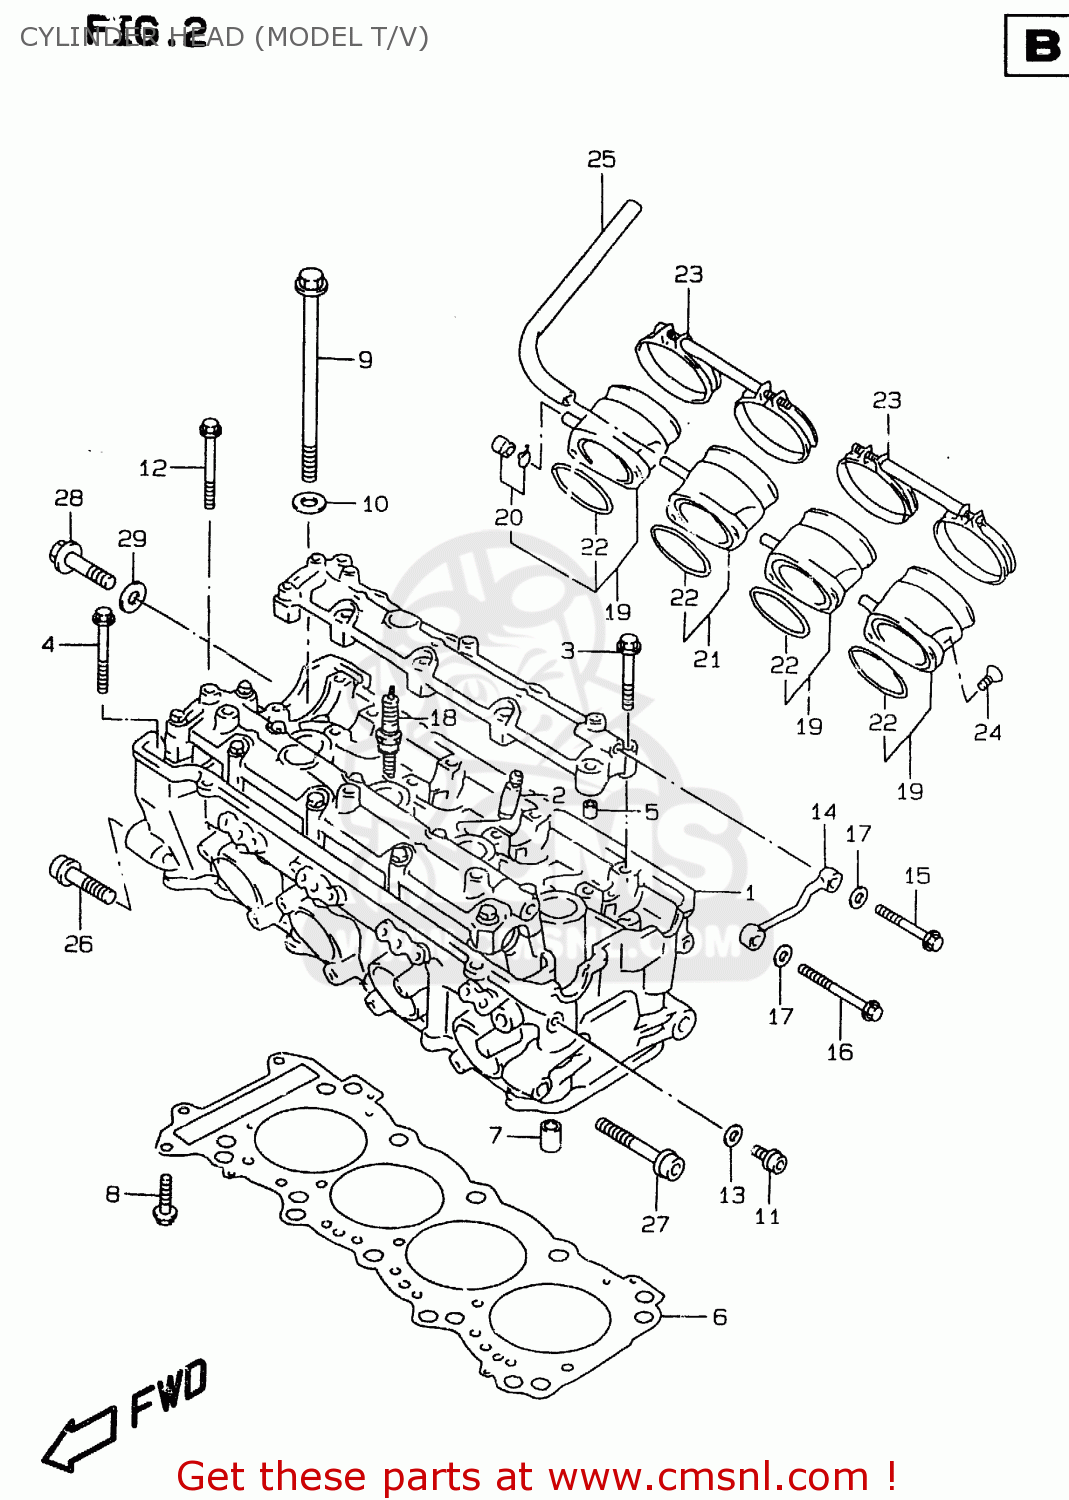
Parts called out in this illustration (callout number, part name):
1	HEAD ASSEMBLY,CYLINDER
2	GUIDE,VALVE
3	BOLT(6X39)
4	BOLT(6X45)
5	PIN(6.2X8X16)
6	GASKET,CYLINDER HEAD (T
7	PIN
8	BOLT
9	BOLT(10X160)
10	WASHER(10.5X19X2)
11	BOLT
12	BOLT,CYL.OIL P
13	GASKET(5.8X13X1.2) (NAS)
14	PIPE,CYLINDER HEAD OIL
15	BOLT
16	BOLT (6X45)
17	WASHER
18	PLUG,SPARK(CR8E)
19	PIPE ASSY,INTAKE
20	CAP
21	PIPE ASSY,INTAKE NO.3
22	O RING(D:2.4,ID:44)
23	CLAMP,INTAKE PIPE
24	SCREW
25	HOSE,VACUUM
26	BOLT
27	BOLT
28	BOLT,CYL HEAD SIDE FACE
29	WASHER,HEAD COVER
